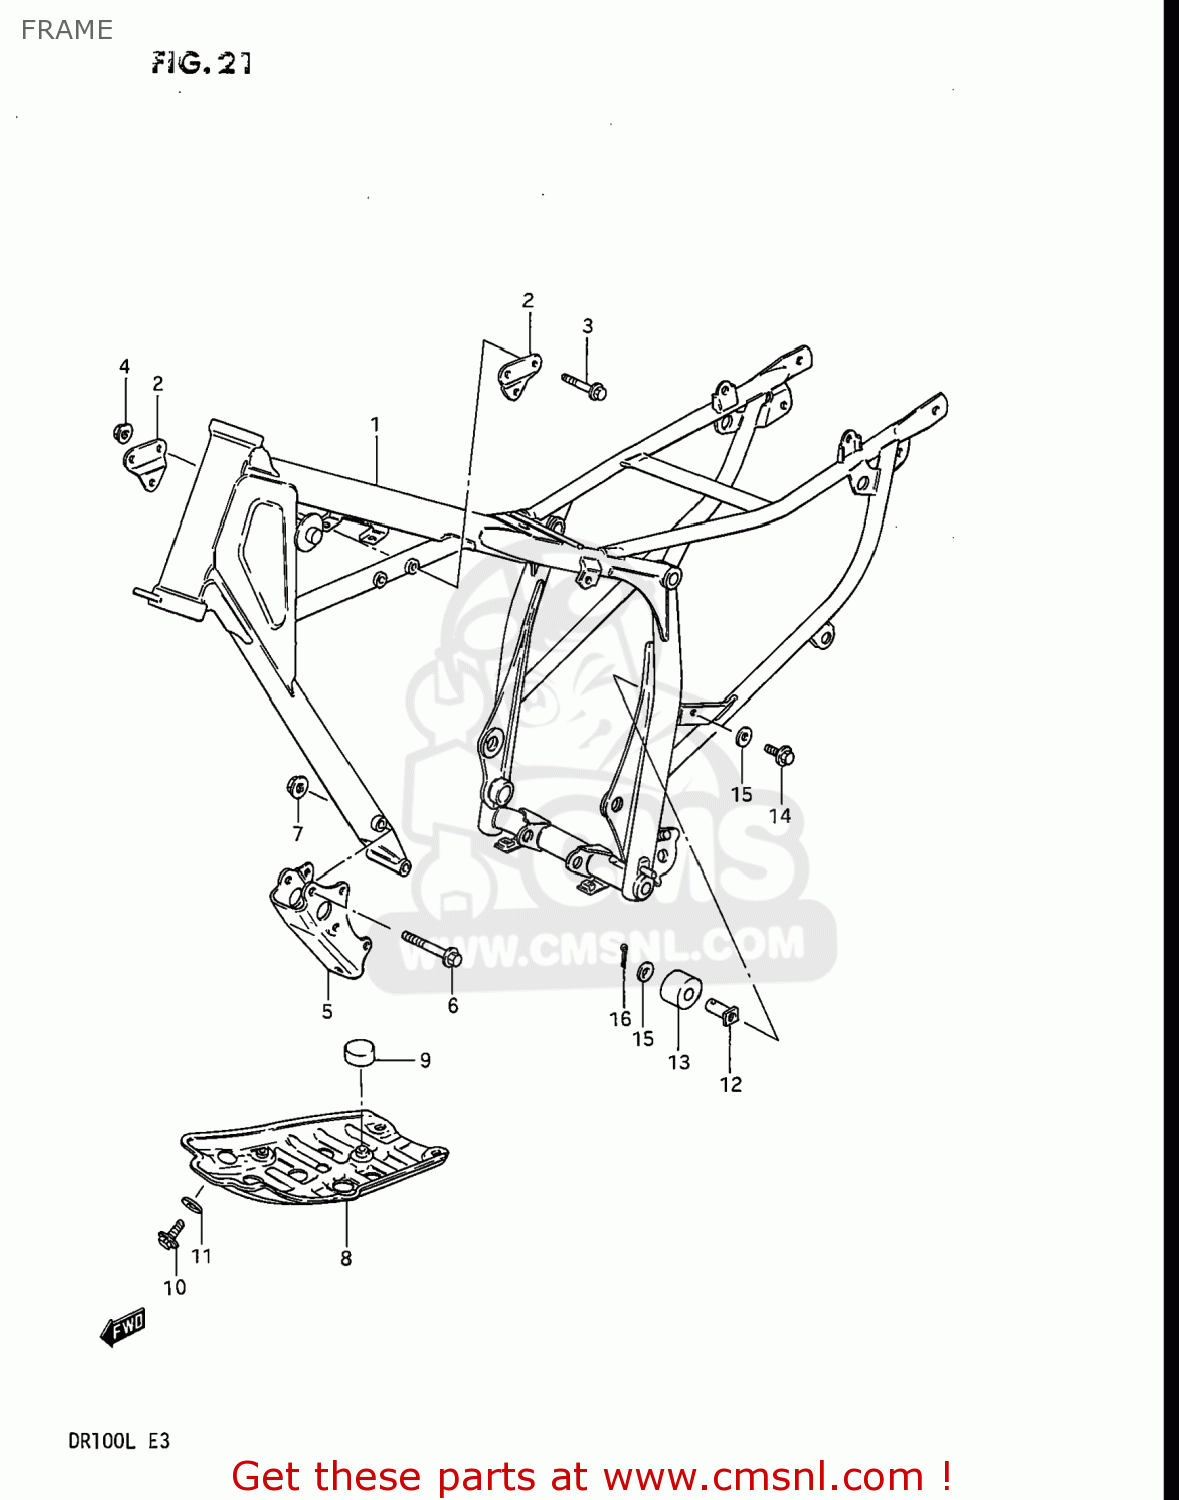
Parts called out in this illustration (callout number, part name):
1	FRAME
2	PLATE,ENGINE MOUNTING
3	BOLT 8X50
4	NUT
5	PLATE,ENGINE MOUNTING
6	BOLT 8X67
7	NUT
8	PROTECTOR,ENGINE
9	CUSHION
10	BOLT 6X12
11	WASHER
12	BOSS,CHAIN CONTROL
13	ROLLER,CHAIN LENGTH CONTROLLER
14	BOLT
15	WASHER
16	PIN 25X20
